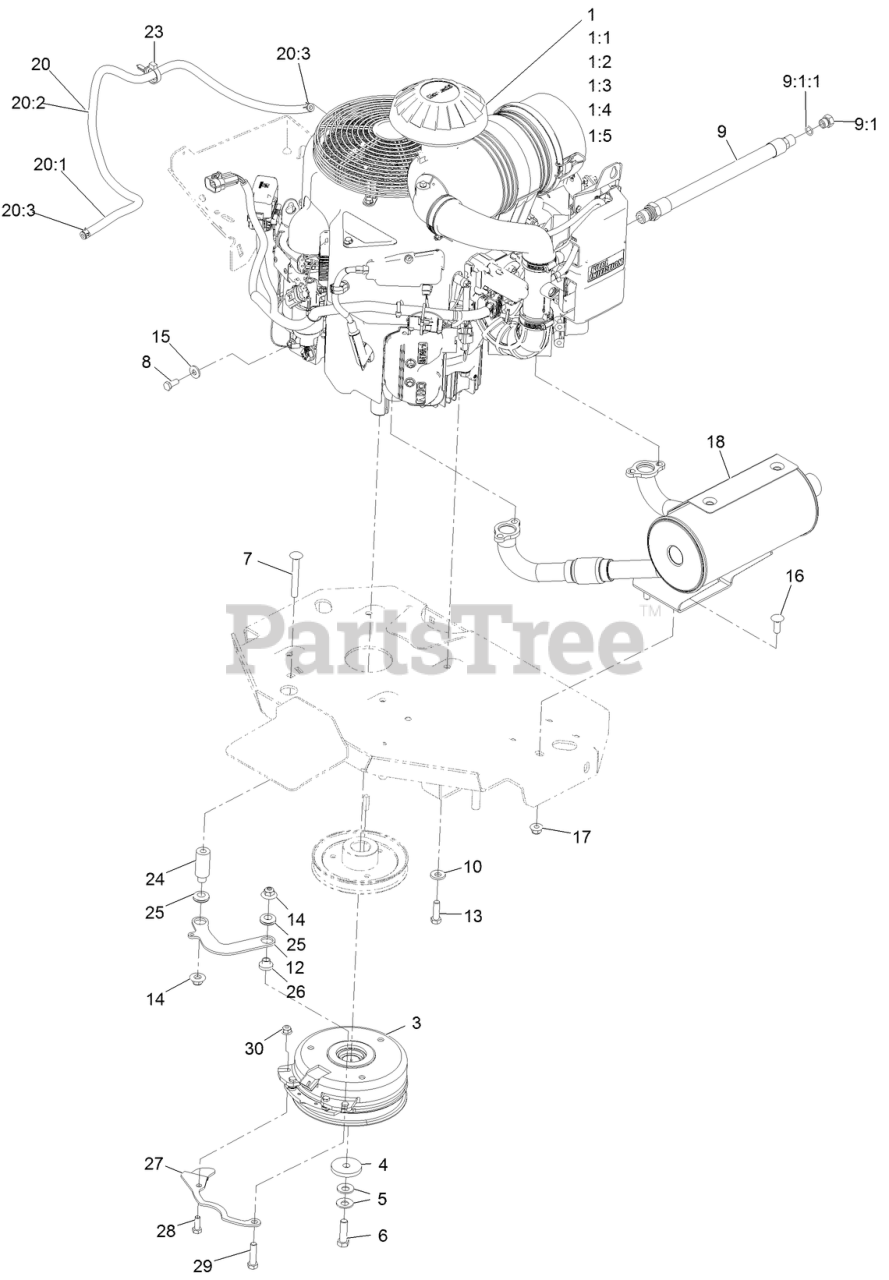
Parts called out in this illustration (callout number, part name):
1:1	KAWASAKI 49065-2078 ENGINE OIL FILTER
1:3	KAWASAKI 49019-0031 FUEL FILTER
1:4	KAWASAKI 11013-7039 SAFETY FILTER
1:5	KAWASAKI 11013-7038 AIR FILTER
3	CLUTCH KIT
4	WASHER-CLUTCH
5	WASHER-SPRING
6	SCREW-HH, W/LOCTITE
7	SCREW-CARR
8	SCREW-HH
9	ENGINE OIL DRAIN HOSE ASM
9:1	PLUG-HH
9:1:1	O-RING
10	WASHER-BELLEVILLE
12	LINK-ANCHOR, CLUTCH
13	SCREW-HH
14	NUT-FLANGE, NI
15	WASHER-SPRING
16	SCREW-CARR
17	NUT-HF, NI
18	MUFFLER, FX850/801 FLEX
20	FUEL LINE ASM
20:1	HOSE-FUEL
20:2	SLEEVE-THERMAL
20:3	CLAMP-HOSE
23	CLAMP-HOSE
24	SPACER
25	GROMMET-RUBBER
26	SPACER
27	BELT-GUIDE
28	SCREW-HH
29	SCREW-HH
30	NUT-HF, NI
